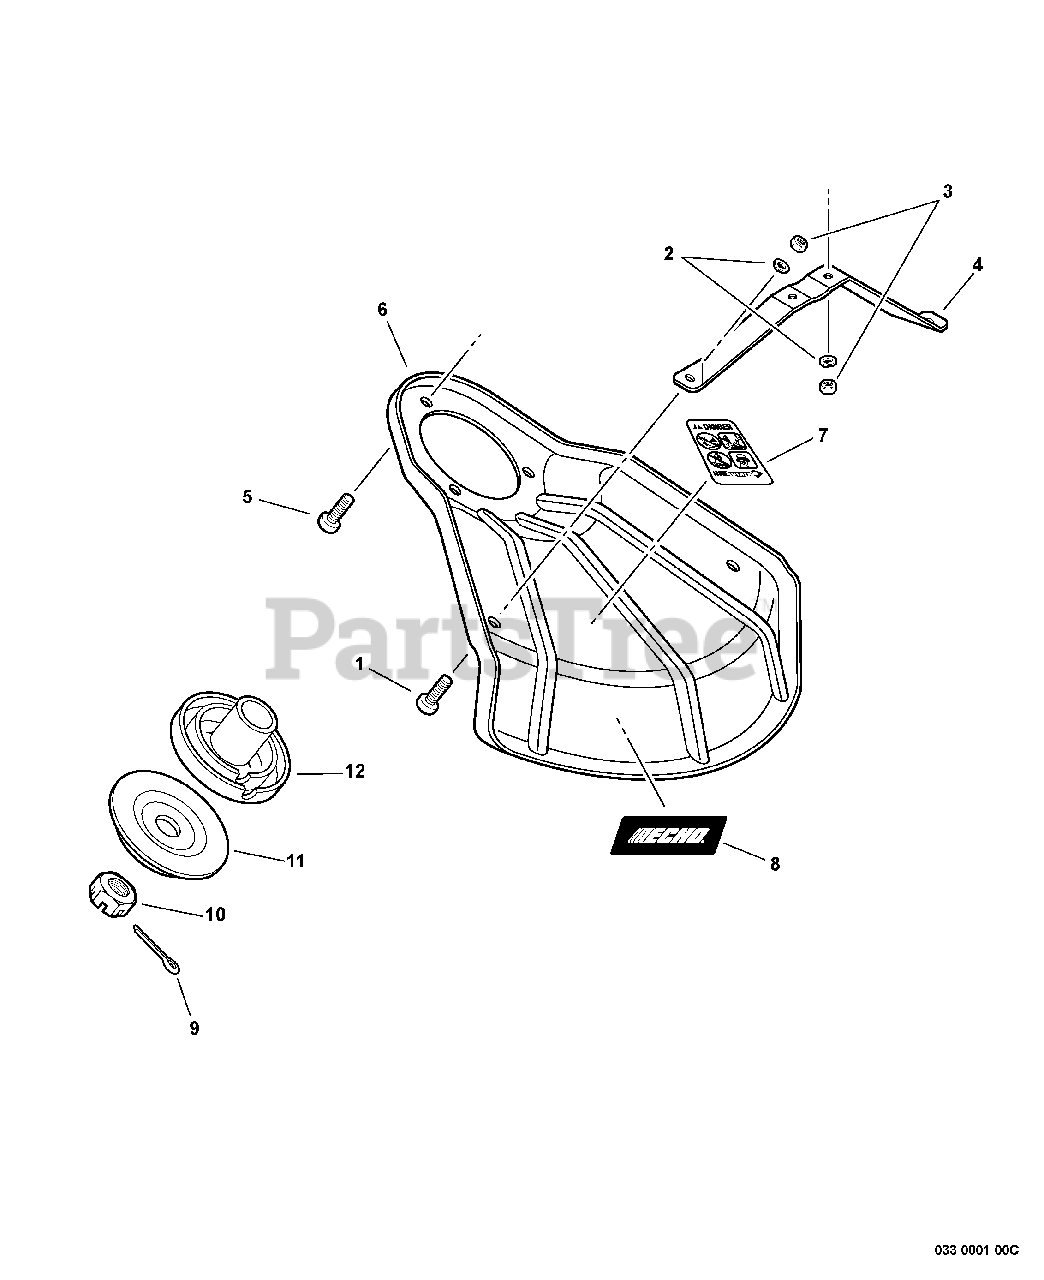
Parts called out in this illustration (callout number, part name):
1	SCREW - 5X8
2	LOCKWASHER - 5
4	BRACKET, SHIELD
5	SCREW - 5X10
6	SHIELD, DEBRIS - METAL
7	LABEL - DANGER
8	LABEL - ECHO
9	PIN, SPLIT - 2X22
10	NUT - 10 -- LEFT HAND
11	ADAPTOR, BLADE - LOWER
12	ADAPTOR, BLADE - UPPER
